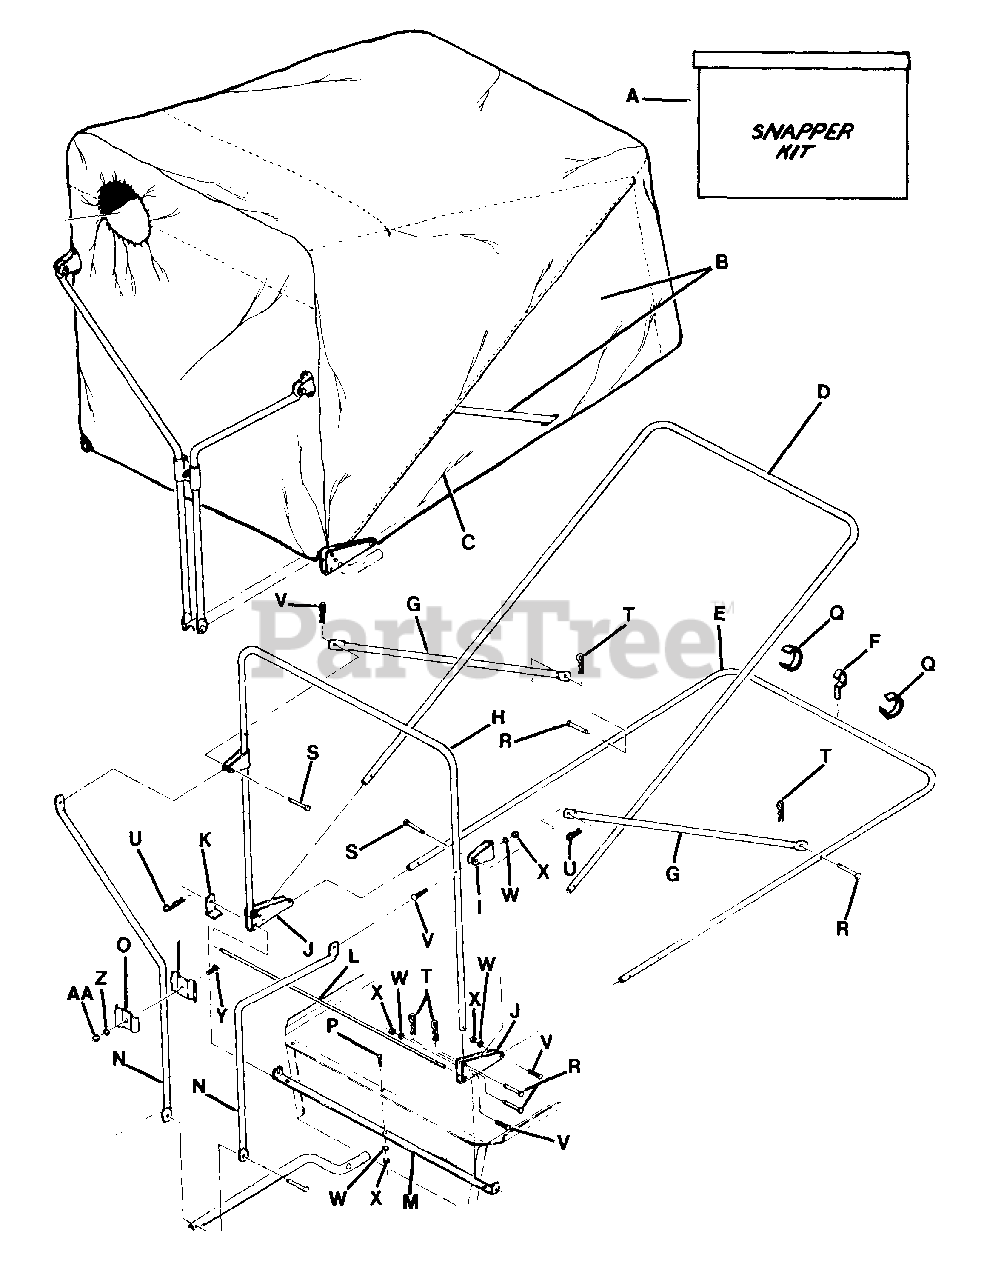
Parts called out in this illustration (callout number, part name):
A	KIT, WAGON COVER
B	FRAME/CANOPY ASSEMBLY
C	CANOPY - CLOTH ONLY
D	FRAME, CENTER
E	FRAME, BASE
F	LOCK, CANOPY
G	BRACE, FRAME
H	FRAME, FRONT
I	CLAMP, ROD
J	BRACKET, CORNER
K	CLIP, HINGE
L	PIN, HINGE
M	MOUNT, HINGE
N	STRUT, FRAME
O	CLAMP, STRUT
P	BOLT, CARRIAGE 1/4-20x3/4
Q	BUSHING, PLASTIC (WEAR PADS)
R	PIN, 1/4x1-1/8 CLEVIS
S	PIN, 5/16 CLEVIS
T	PIN, 1/4 "HAIR"
U	PIN, HAIR
V	BOLT, CARRIAGE 1/4-20x1
W	WASHER, 1/4 INTERNAL TOOTH LOCK
X	NUT, 1/4-20 HEX
Y	SCREW, HEX HEAD CAP 3/8 -24x1
Z	WASHER, 3/8 SPLIT LOCK
AA	NUT, 3/8-24 HEX
